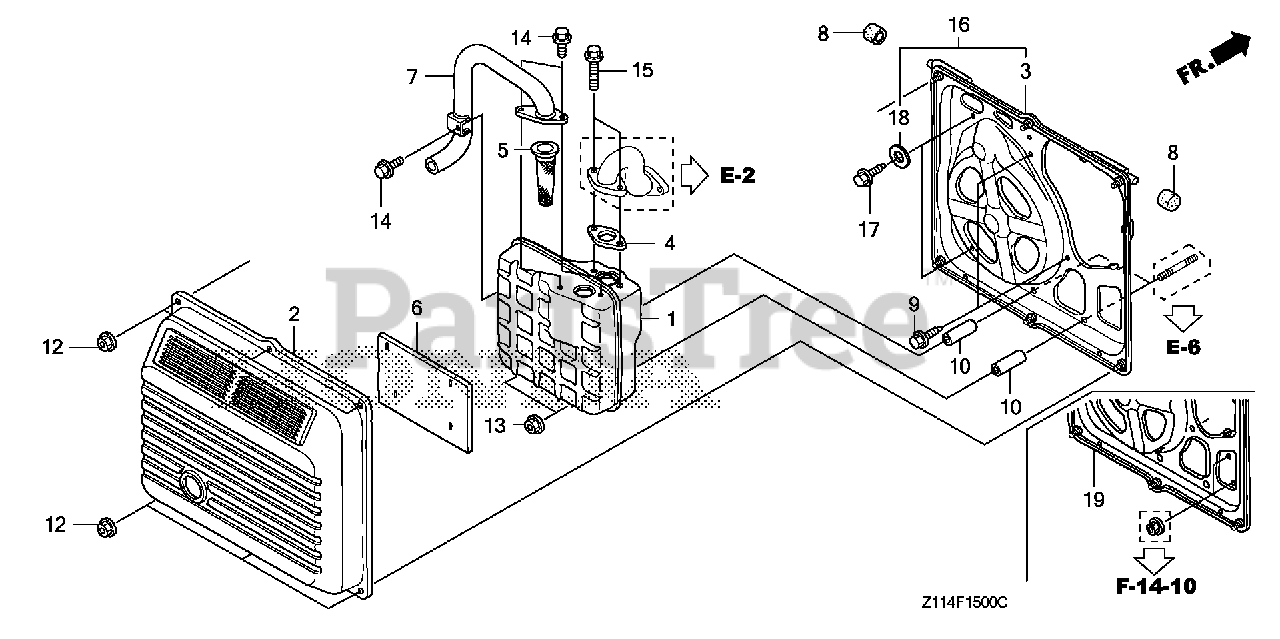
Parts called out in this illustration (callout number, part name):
2	PROTECTOR, MUFFLER (OUTER) *NH105* (MAT BLACK)
3	PROTECTOR KIT, MUFFLER (INNER)
3	PROTECTOR, MUFFLER (INNER)
4	GASKET, EX. PIPE
5	ARRESTER, SPARK
6	INSULATOR, MUFFLER PROTECTOR (A)
7	PIPE, EX. TAIL
8	RUBBER, STOPPER
9	BOLT, FLANGE (6X12) (CT200)
10	COLLAR, MUFFLER
12	NUT, FLANGE (6MM)
13	NUT, FLANGE (8MM)
14	BOLT, FLANGE (6X10)
15	BOLT, FLANGE (8X20) Use up to Engine SN 1609606.
16	PROTECTOR KIT, MUFFLER (INNER)
17	BOLT, FLANGE (6X12) (CT200)
17	BOLT, FLANGE (8X16) Use from Engine SN 1000016.
18	WASHER, PLAIN (6MM)
